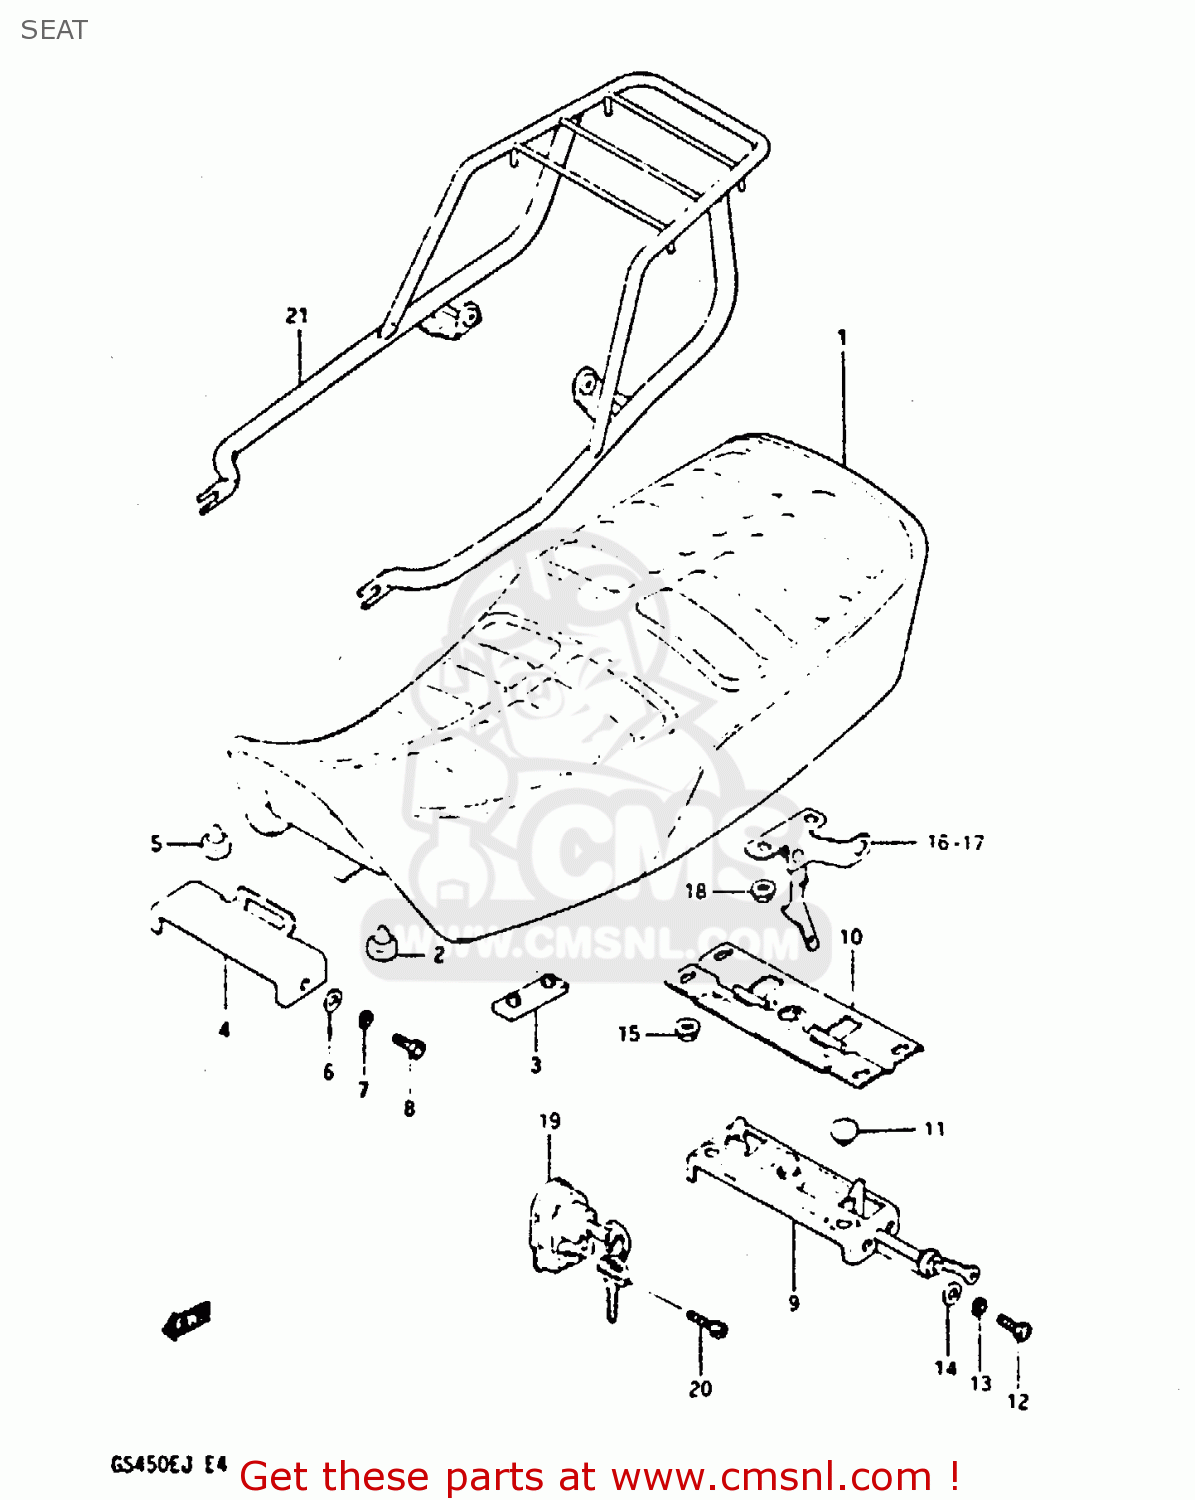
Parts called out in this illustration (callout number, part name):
1	SEAT ASSEMBLY
2	CUSHION
3	CUSHION
4	PLATE,SEAT LOCK,FRONT
5	CUSHION(11.5X22X20)
6	WASHER, LOWER
7	WASHER,LOCK
8	BOLT
9	PLATE,CLAMP GUIDE
10	PLATE,SEAT CLAMP GUIDE
11	CUSHION
12	SCREW 5X10
13	LOCK WASHER
14	WASHER
15	NUT
16	LEVER,SEAT HOOK,RIGHT
17	LEVER,SEAT HOOK,LEFT
18	NUT
19	LOCK ASSY,HELMET
20	BOLT
21	CARRIER
